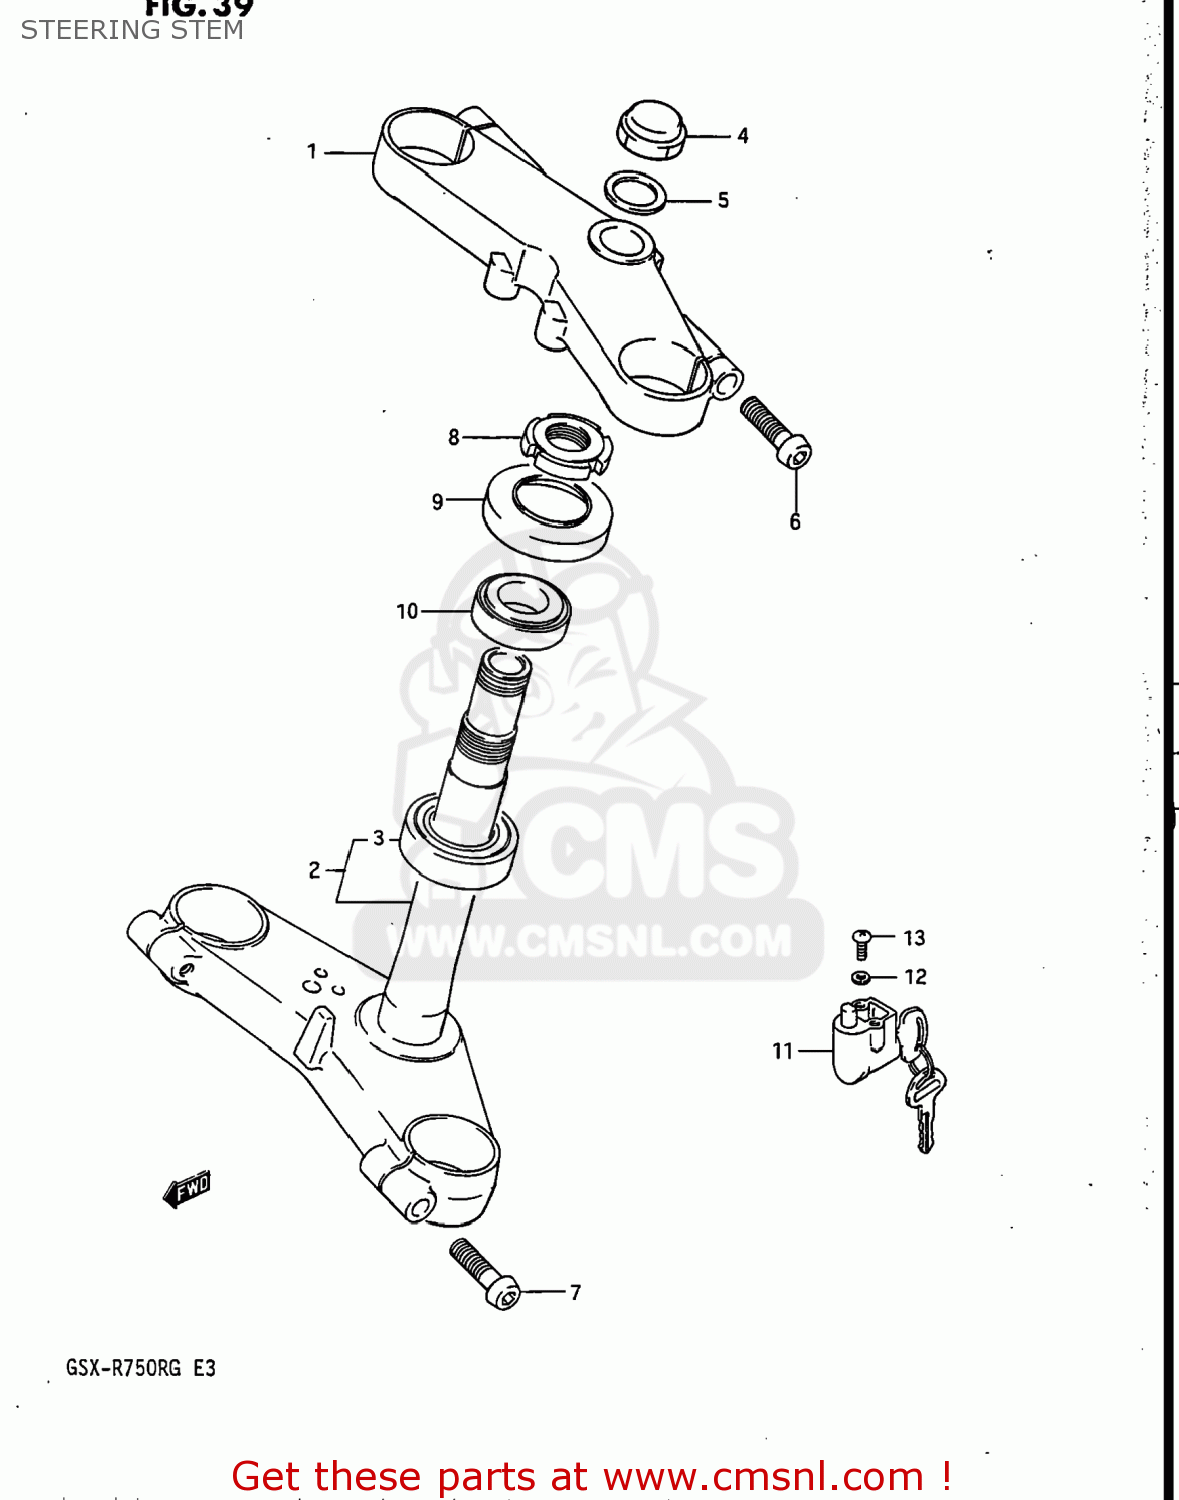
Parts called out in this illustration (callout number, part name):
1	HEAD,STEERING STEM
2	STEM,STEERING
3	BEARING
4	NUT,STEM HEAD
5	WASHER,STEERING STEM
6	BOLT,UPPER
7	BOLT,FORK INNER TUBE F
8	NUT,STEERING STEM(25X44X10)
9	DUST SEAL,STEERING UPR
10	TAPER,ROLLER BEARING
11	LOCK ASSY,STEERING
12	LOCK WASHER
13	SCREW 5X20
